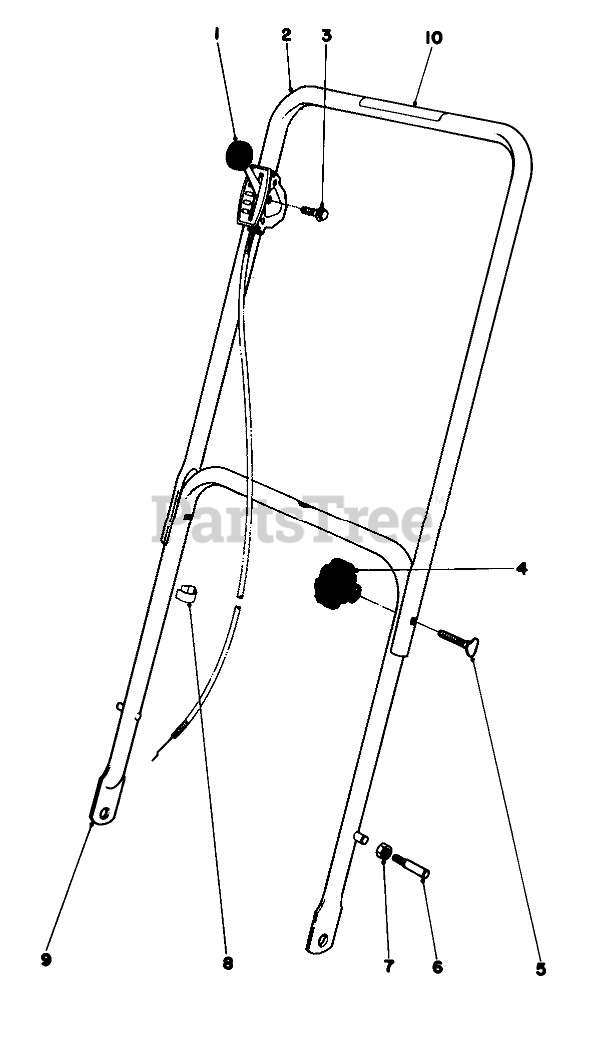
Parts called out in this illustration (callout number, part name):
1	Throttle Control
2	UPPER HANDLE
5	HANDLE SCREW
6	HANDLE PIN
7	Nut
8	BOWDEN CLIP
9	Lower Handle
10	Decal
